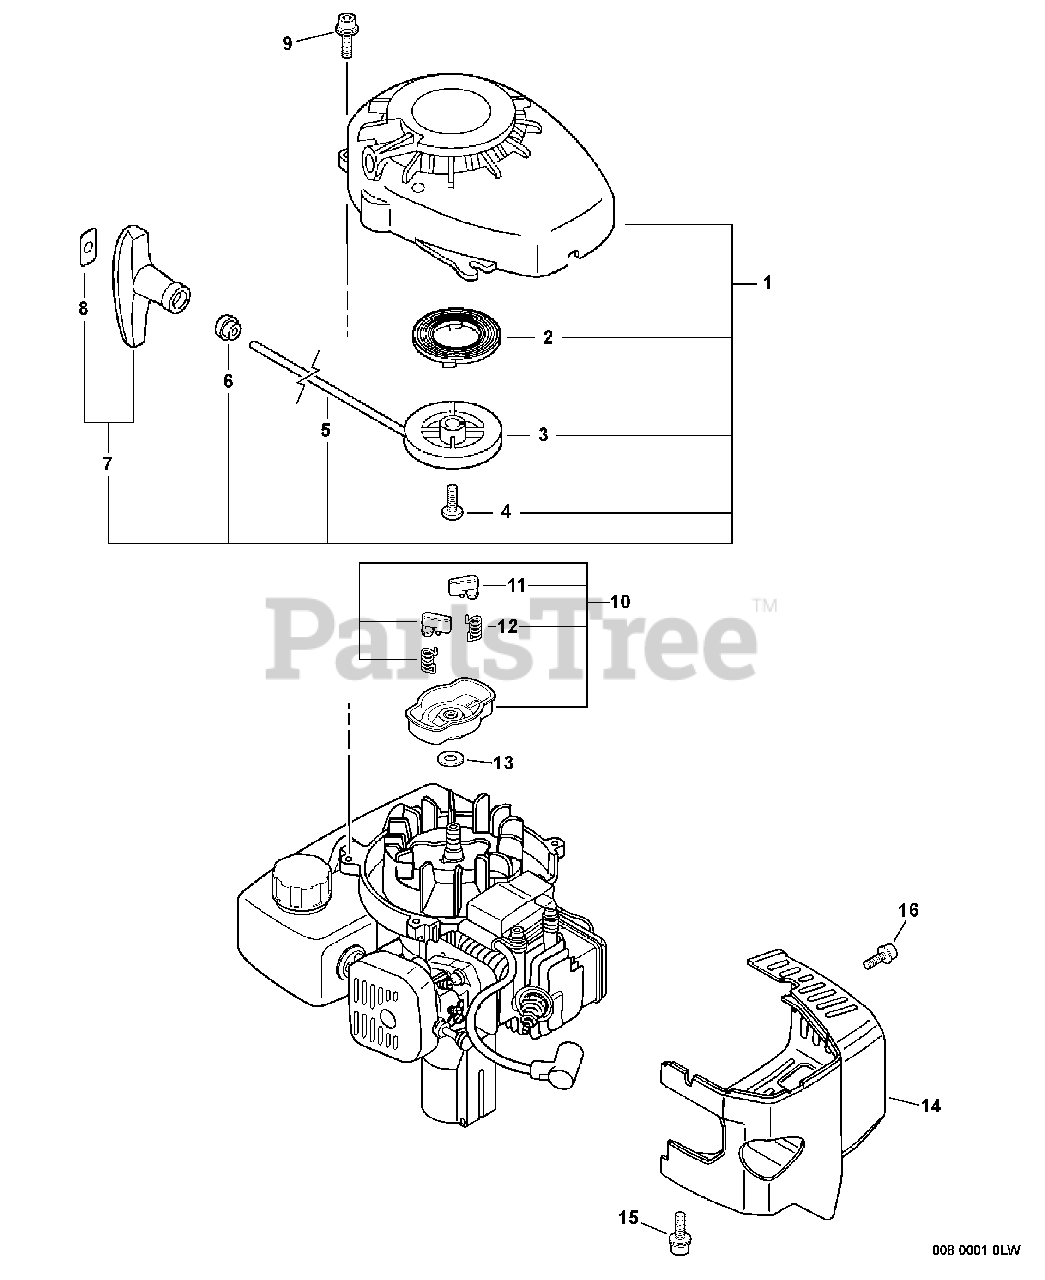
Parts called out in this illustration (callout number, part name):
1	STARTER ASSY
2	SPRING, RECOIL
3	REEL, ROPE
4	SCREW
5	ROPE, STARTER
6	GUIDE, ROPE
7	GRIP, STARTER
8	RETAINER, ROPE
9	SCREW 4×16
10	PAWL ASSY, STARTER
11	PAWL, STARTER - BLACK
12	SPRING, RETURN
13	WASHER, SPRING 8
14	COVER, ENGINE
15	SCREW 4×18
16	BOLT 4×8
